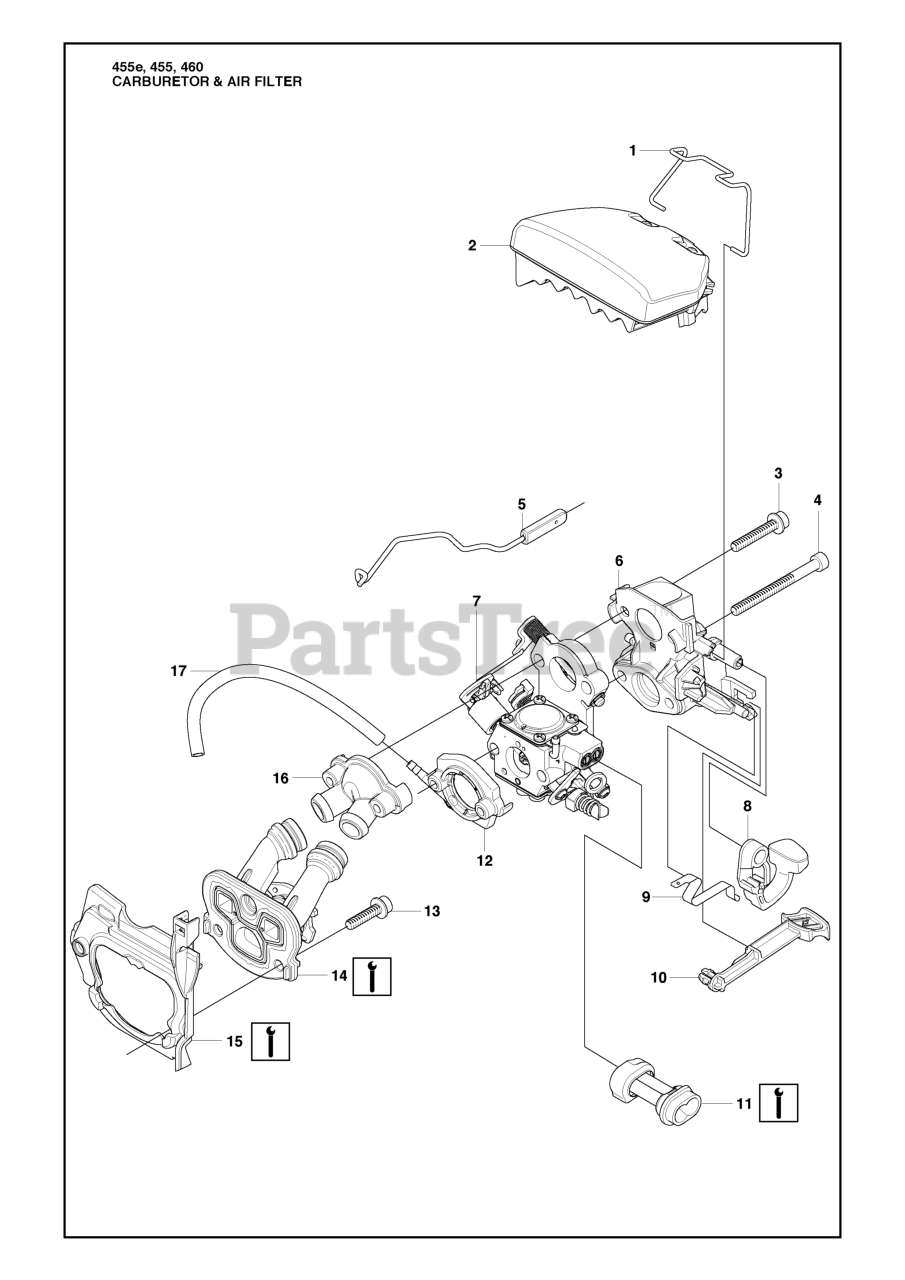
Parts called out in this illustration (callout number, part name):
2	AIR FILTER
5	THROTTLE ROD
6	FILTER HOLDER
7	CARBURETOR
8	STOP LEVER
10	CHOKE CONTROL
11	GUIDE SLEEVE CARB
14	INLET PIPE
17	FUEL HOSE
